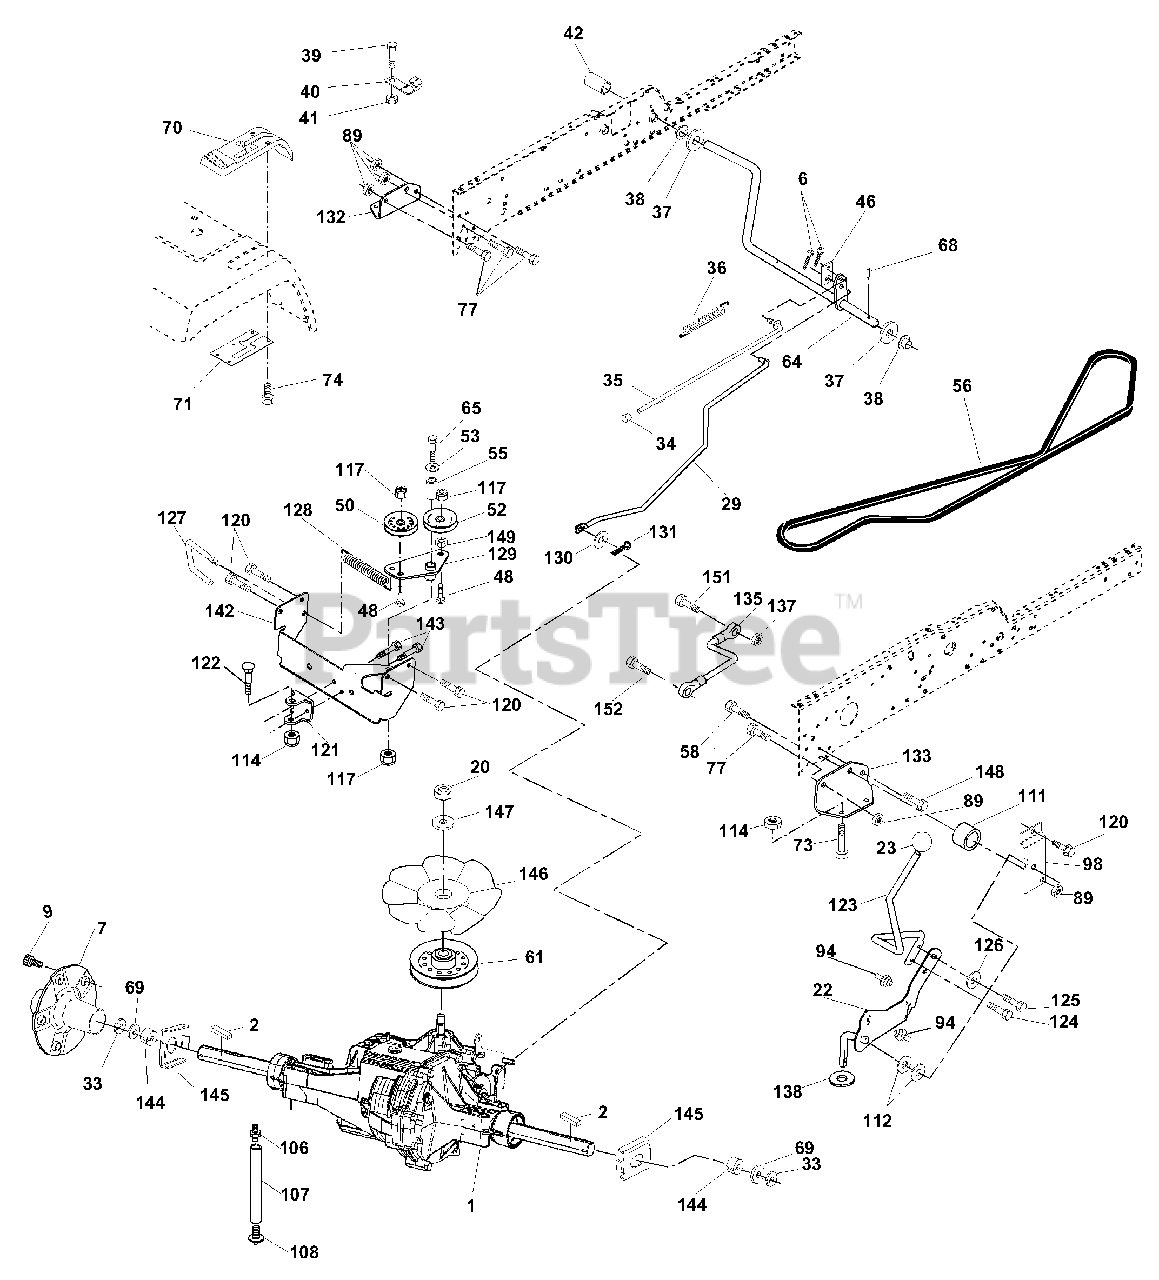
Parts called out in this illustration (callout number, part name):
2	Key Sq. 1/4 x 1/4 x 2
6	Pin, Cotter
7	Wheel, Hub Assembly
22	Lever Asm Shift
29	Brake, Rod
34	Cap, Parking Brake
35	Rod, Parking Brake
36	Spring, Drive Ground
37	Washer 25/32 x 1-1/4 x 16 Ga.
39	Screw, Fin. #10-24 x 1
40	Actuator, Interlock VGT
41	Nut Centerlock 10-24 Unc
42	Cover, Pedal
46	Retainer, Spring
48	Bolt Rdhd 3/8-16 x 1.3/4 Gr. 5
50	Pulley, Idler, Flat
52	Pulley, Idler, Grooved
53	Washer,Hardened
55	Bearing, Idler
58	Bolt Fin Hex 7/16-14 x 1-1/2
61	Pulley, Transaxle
64	Shaft, Brake Pedal
65	Bolt, Shoulder
70	Console Automatic YT/GT
71	Plate Console Shift
73	Bolt Hex Flghd 5/16-18 x 3 Gr5
74	Screw Hex Wsh. Hi-Lo 1/4-1/2
77	Bolt Fin Hex 7/16-14 x 1
89	Nut Crownlock 7/16-14 Unc
94	Fastener Christmas Tree
98	Bracket Shift
106	O-Ring Asm Hydro Gear
107	Line Fuel Hydro 15" VGT
108	Cap Asm Vent Hydro Gear
111	Spacer Shift Lever VGTH
112	Washer Nylon High Temp
114	Nut Lock Hex W/Ins 5/16-18 Unc
117	Nut, Lock Flg. 3/8-16
120	Screw 3/8-16 x .75
121	Bracket Strap Torque
122	Bolt RDHDSQ 5/16-18 Unc x 2-1/2
124	Bolt Shoulder 5/16-18 x .561
125	Screw 5/16-18 x 5/8
126	Washer SRRTD 5/16 ID x 1.0 x .125
127	Link Control Clutch
128	Spring Drive GRND
129	Bracket Asm Idler Tensioning
130	Washer 13/32 x 5/8 x 16 Ga.
131	Pin Cotter 3/32 x 3/4
132	Bracket Mtg Hydro 3500 LH VGT
133	Bracket Mtg Hydro 3500 RH VGT
135	Link Asm Control Hydro 3500
137	Nut Lock 5/16-18 NC Thd.
138	Washer Thrust 5/8 x 1.10 x 1/32
142	Strap Torque HG-3500
144	Washer Spacer Axle HG-3000
145	Washer Axle Flange HG-3000
146	Fan 7" Hydro
148	Screw 3/8-16 x 1.0
149	Washer 13/32 x 7/8 x 10 Ga.
151	Retainer Stud 5/16
152	Bolt Hex 5/16 x 1 W/Patch
